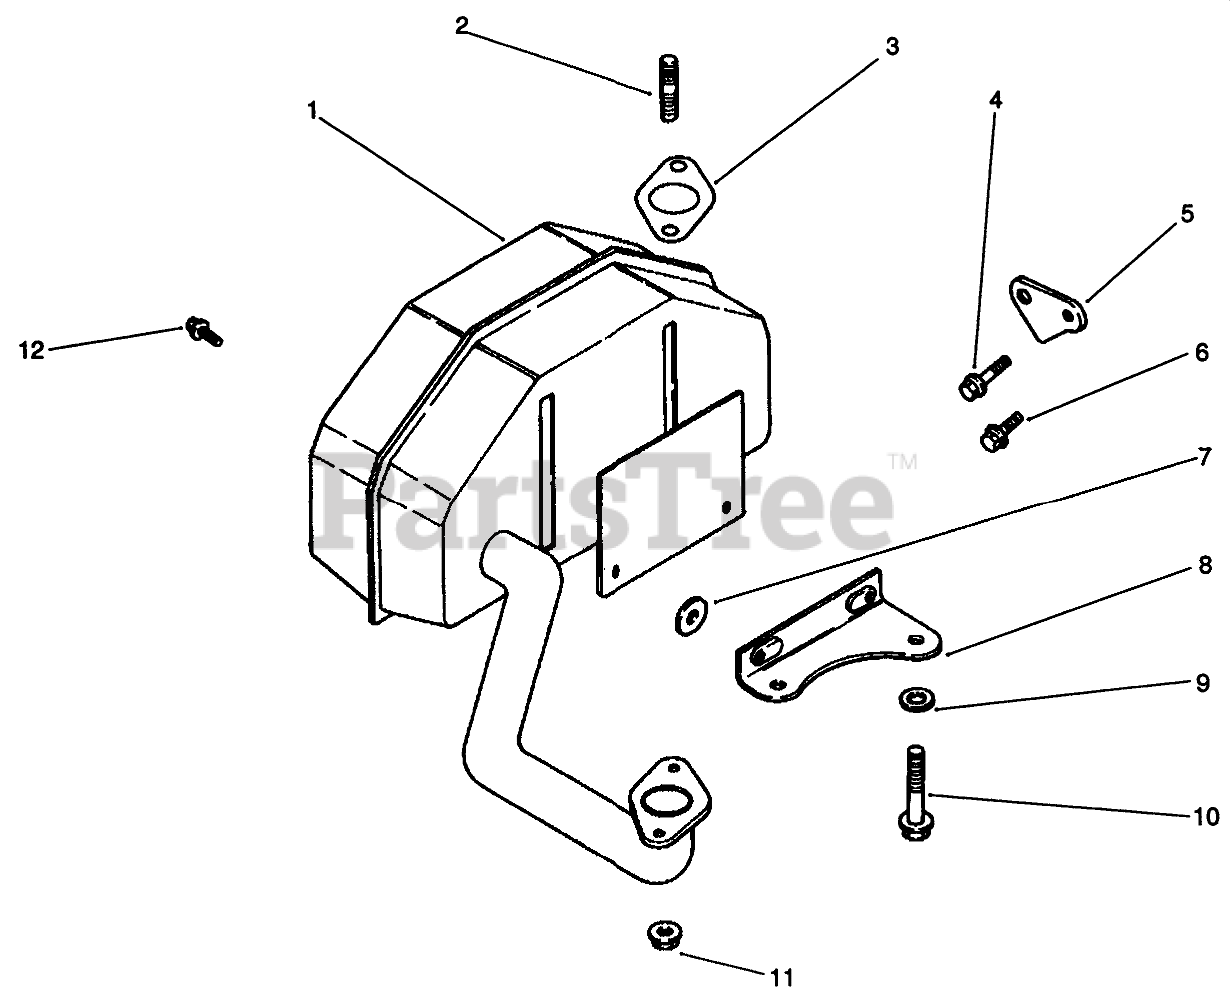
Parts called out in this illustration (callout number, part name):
1	Muffler
2	Stud
3	Gasket-Exhaust
6	Screw
7	Washer
8	Bracket-Muffler
9	Washer
11	Nut-Muffler
12	Screw
